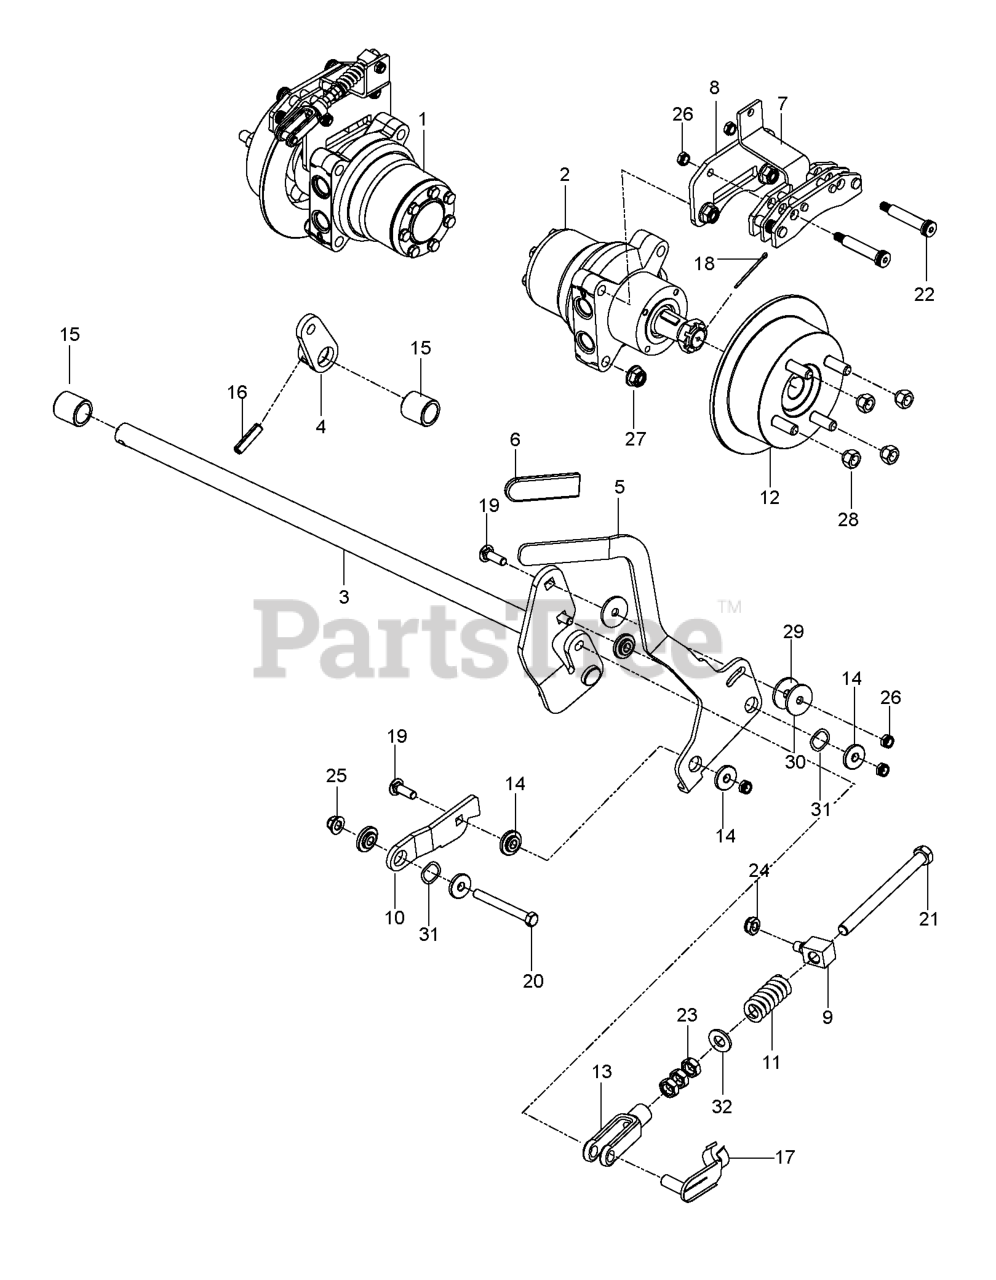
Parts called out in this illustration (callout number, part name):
1	TL15 WHEEL MOTOR
2	MOTOR, TL0240, RT
3	SHAFT, BRAKE WLDMT
4	ARM, RT BRAKE
5	LEVER.BRAKE.BLACK
8	PLATE, CALIPER
9	SWIVEL, BRAKE
10	LINK, FOLLOWER
12	HUB, DISC BRAKE, W/STUDS
13	YOKE-3/8-24 PLTD
14	BUSHING, BRAKE
15	BUSHING, SLEEVE 3/4 X 1.0
16	5/16 DIA ROLL PIN
17	PIN, CLEVIS SPRING, 3/8
18	COTTER PIN 1/8 X 2
19	RHSNB 3/8-16 X 1-1/4
20	HCS 3/8-16 X 3-1/4 GR5 ZD
21	HCS 3/8F X SPECIAL
22	BOLT, SHOULDER, 1/2 X 2.25
23	NUT 3/8-24 JAM
24	5/16-18 THIN PROF NY
25	NUT 3/8-16 HEX FLG NYLOC ZD
26	NUT HEX 3/8-16 NYLON, THIN
27	NUT, 1/2-13 HEX FLG NYLOC ZD
28	LUG NUT 1/2F
29	WASHER, FRICTION, 1/8
30	CONE WASHER
31	WASHER, .825 X 1.087, WAVE
32	WASHER
